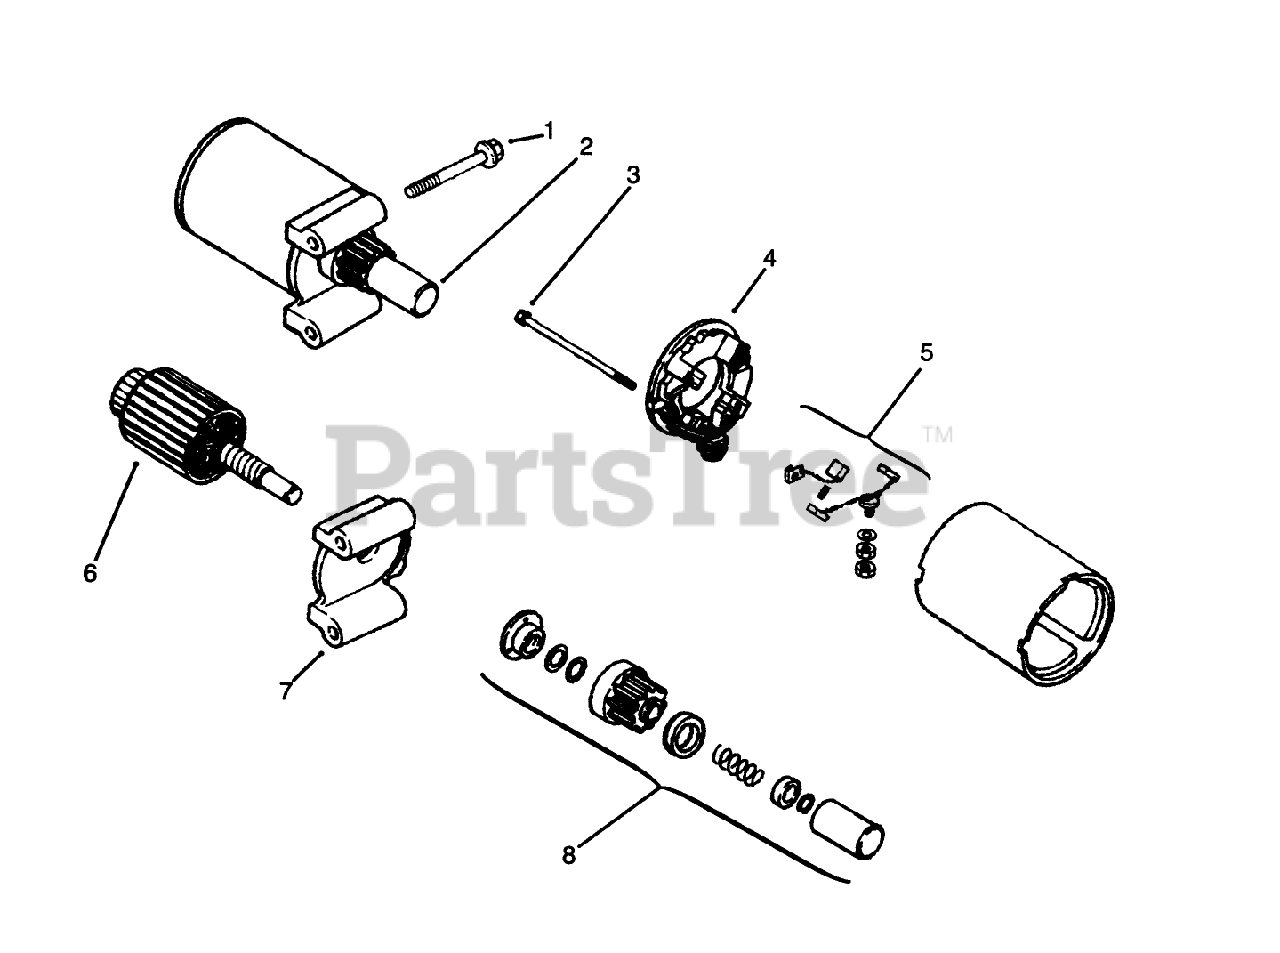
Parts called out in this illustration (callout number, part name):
1	Screw M8x1.25x70 (Only On: 72042, 72063, 72062, 72043)
2	Starter ASM Incl 3-8
3	Screw
4	Cap-Communtator Incl 5
5	Kit-Brush And Spring (Only On: 72042, 72063, 72062, 72043)
6	Armature-Starter
7	Cap-Drive End
8	Kit-Drive
